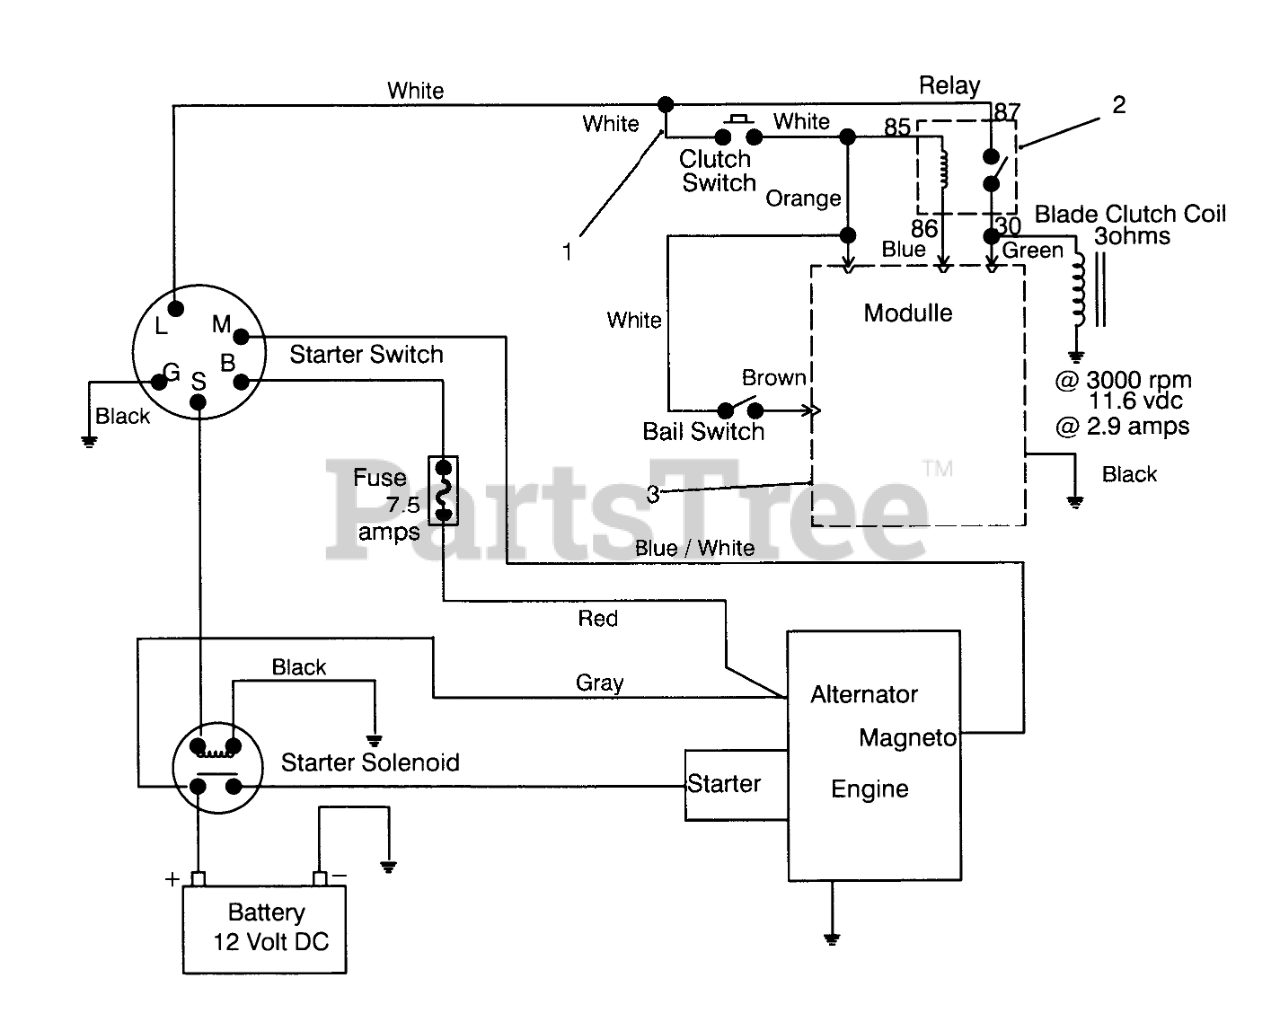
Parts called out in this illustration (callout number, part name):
1	WIRE HARNESS
2	RELAY
3	Module
